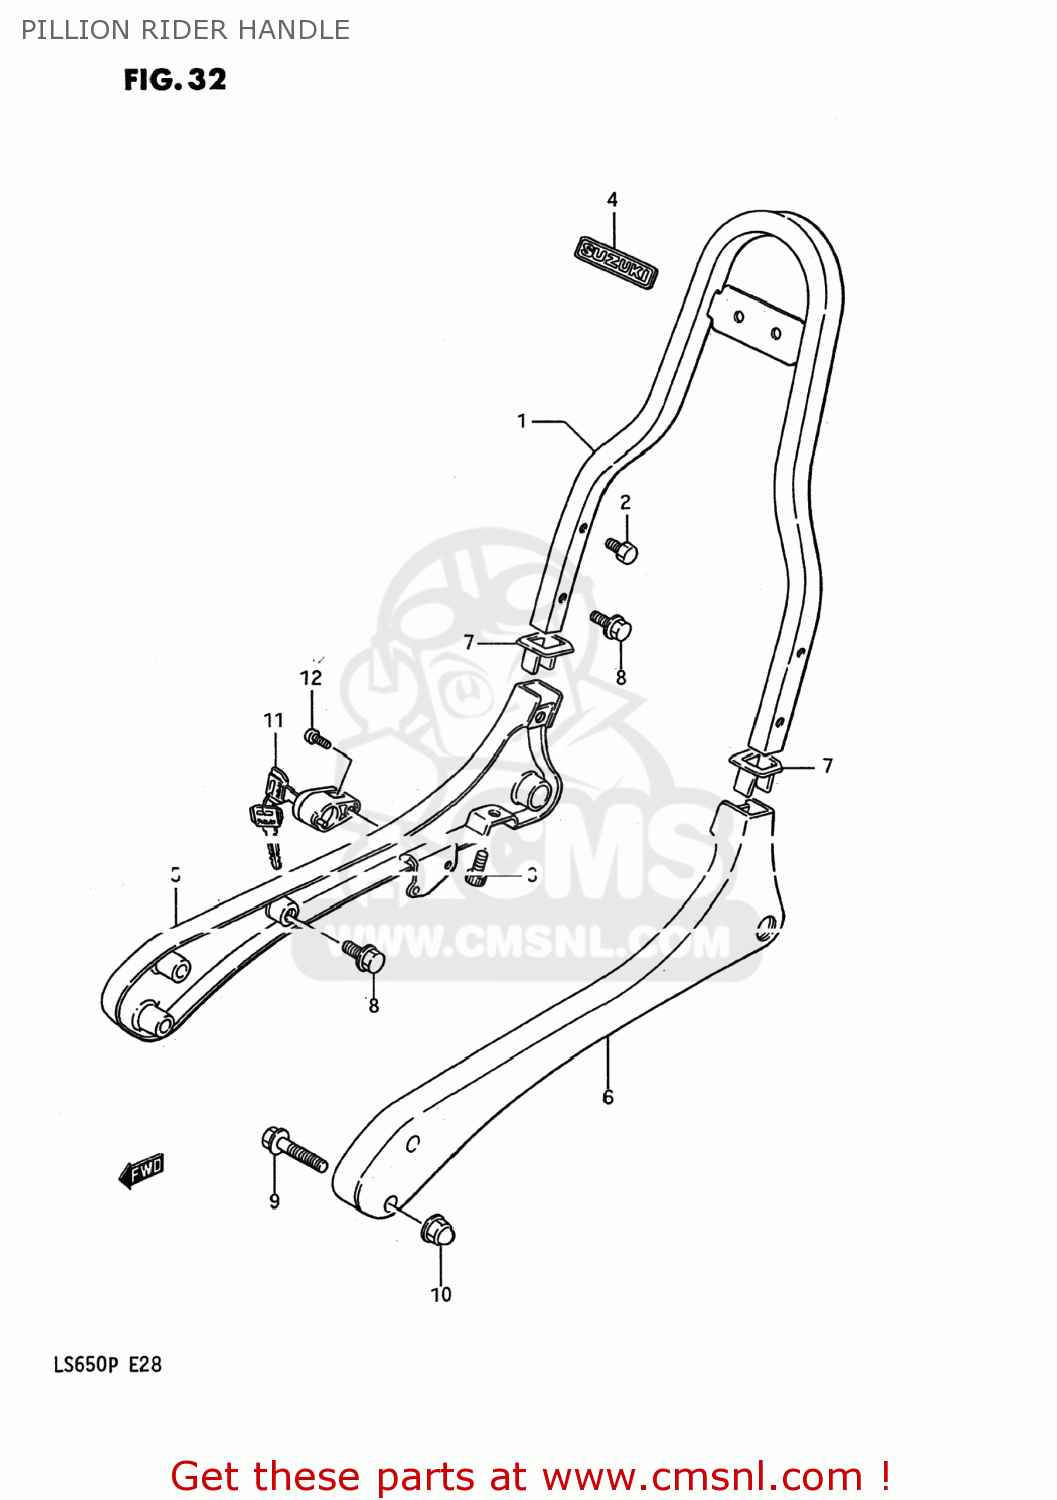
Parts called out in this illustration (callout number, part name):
1	HANDLE,PILLION UPR
2	BOLT
3	BOLT,LOWER
4	EMBLEM
5	HANDLE,PILLION RIDER,R
6	HANDLE,PILLION RIDER,L
7	COVER,PILLION HNDL
8	BOLT
9	BOLT,FRONT
10	NUT 8MM
11	LOCK SET,HELMET
12	SCREW
